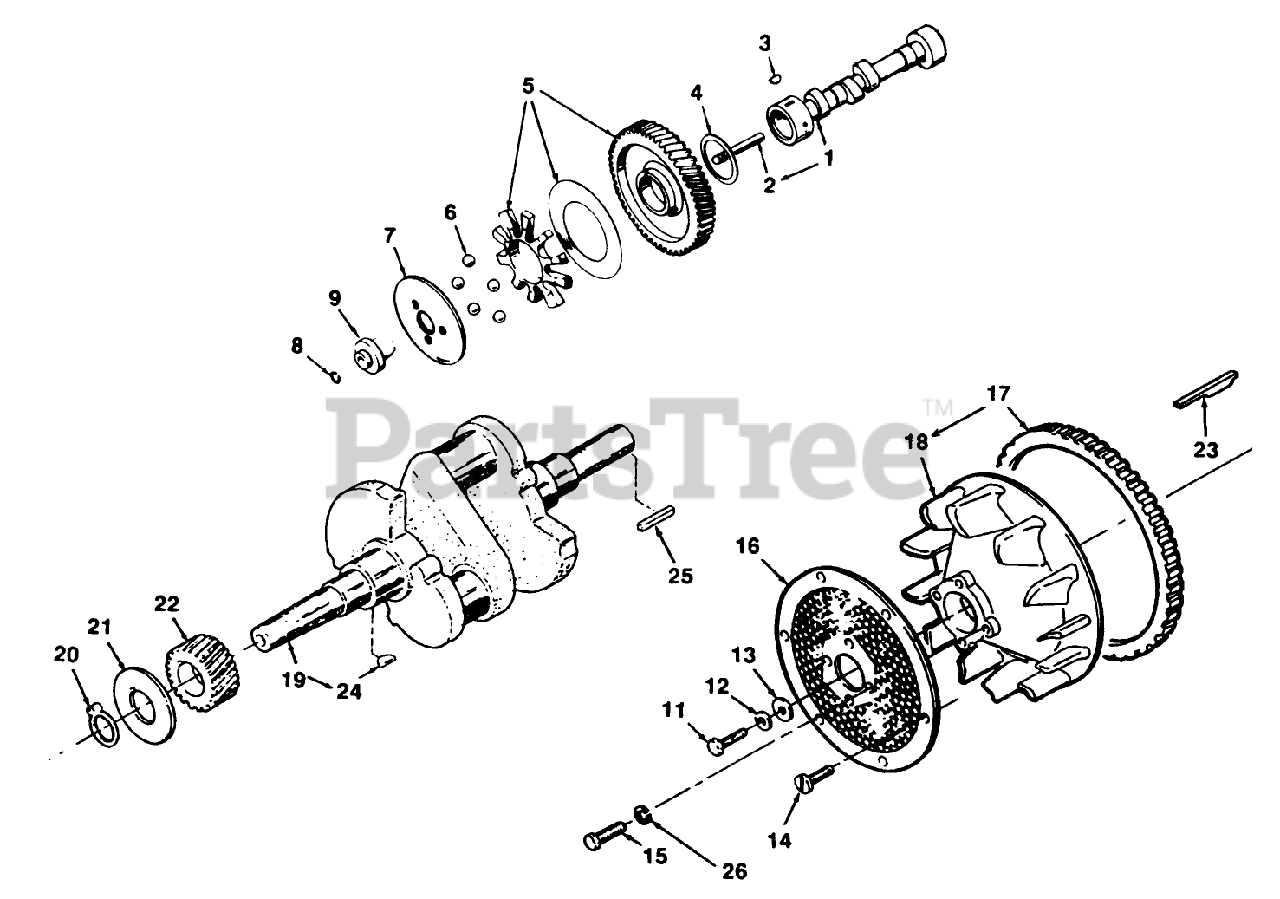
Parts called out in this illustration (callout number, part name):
1	CAMSHAFT
2	PIN-CENTER
4	WASHER-THRUST
6	BEARING
7	CUP-GOVERNOR
9	HUB-GOVERNOR CUP
12	WASHER-FLAT
13	WASHER-FLAT
15	HX HD LOCK CAPSCREW
16	SCREEN-AIR INLET
18	FLYWHEEL
22	GEAR-CRANKSHAFT
23	KEY-FLYWHEEL
